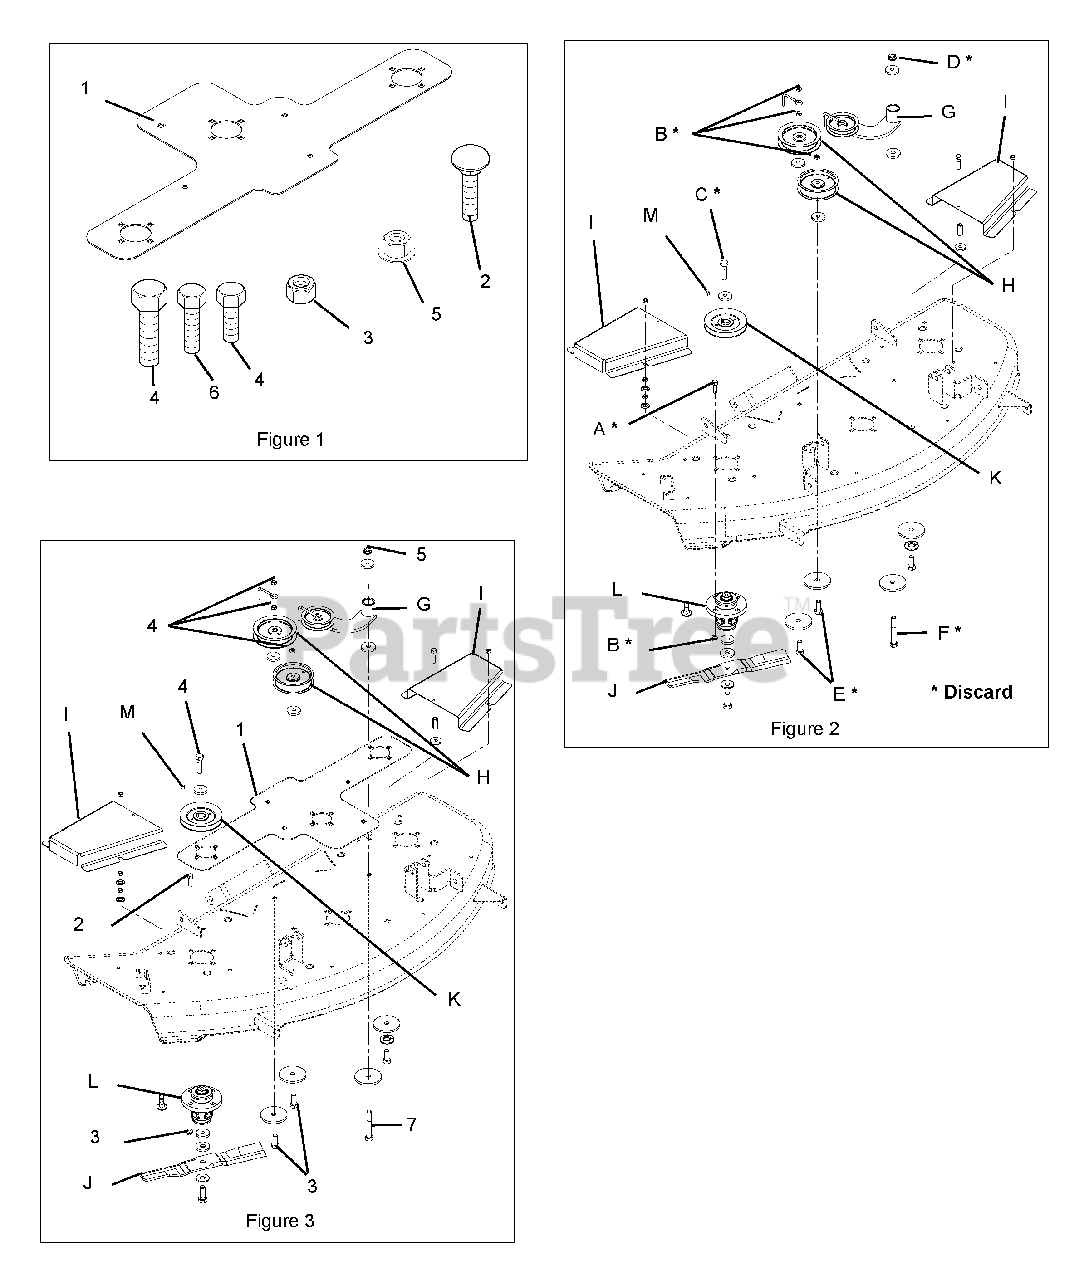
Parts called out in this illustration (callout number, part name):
1	50" Doubler Plate
2	3/8" x 1-1/4" Round Head Square Neck Bolt
3	3/8" Nylon Flange Nut
4	3/8" x 1" Hex Bolt
5	1/2" Top Lock Flange Nut
6	3/8" x 2-3/4" Hex Bolt
7	1/2" x 3-1/2" Hex Bolt
